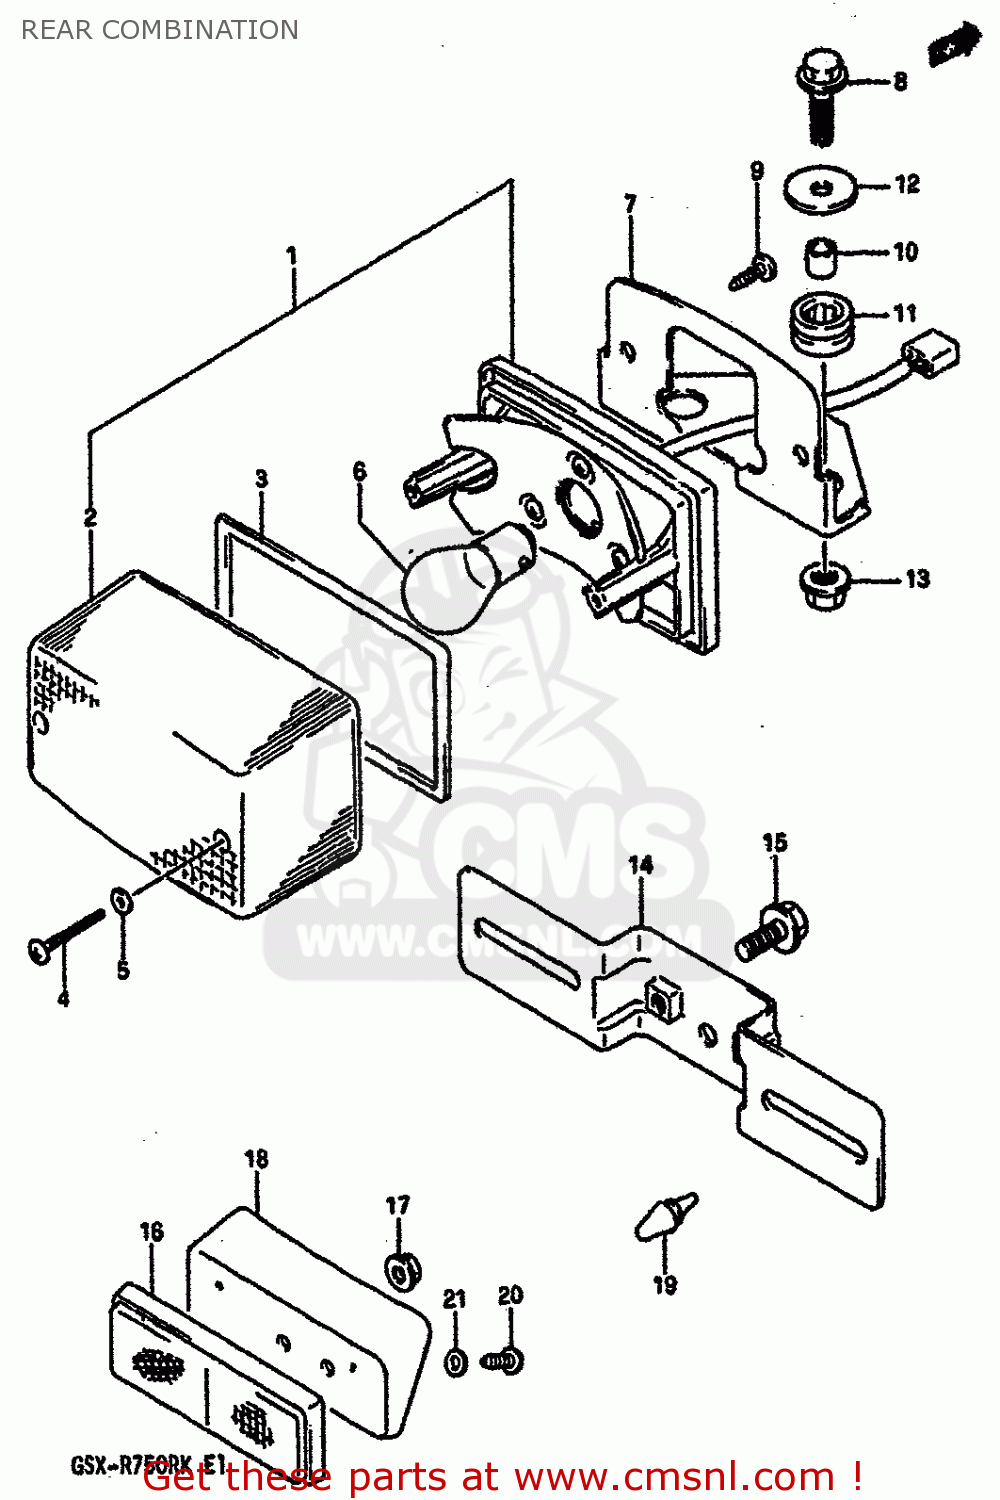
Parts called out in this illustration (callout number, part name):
1	LAMP ASSY,REAR COMBINATION
2	LENS
3	GASKET,RR COMBI LAMP LENS (NAS)
4	SCREW
5	GASKET (NAS)
6	BULB(12V21/5W,BF141-49642A)
7	BRACKET,REAR COMBINATION
8	BOLT
9	SCREW
10	SPACER(6.3X9.1X11.5)
11	CUSHION
12	WASHER (6.5X24X1.2)
13	NUT
14	BRACKET,LICENCE PLATE
15	BOLT
16	REFLECTOR ASSEMBLY,REAR
17	NUT
18	SPACER,RR RR
19	CUSHION
20	SCREW
21	WASHER
